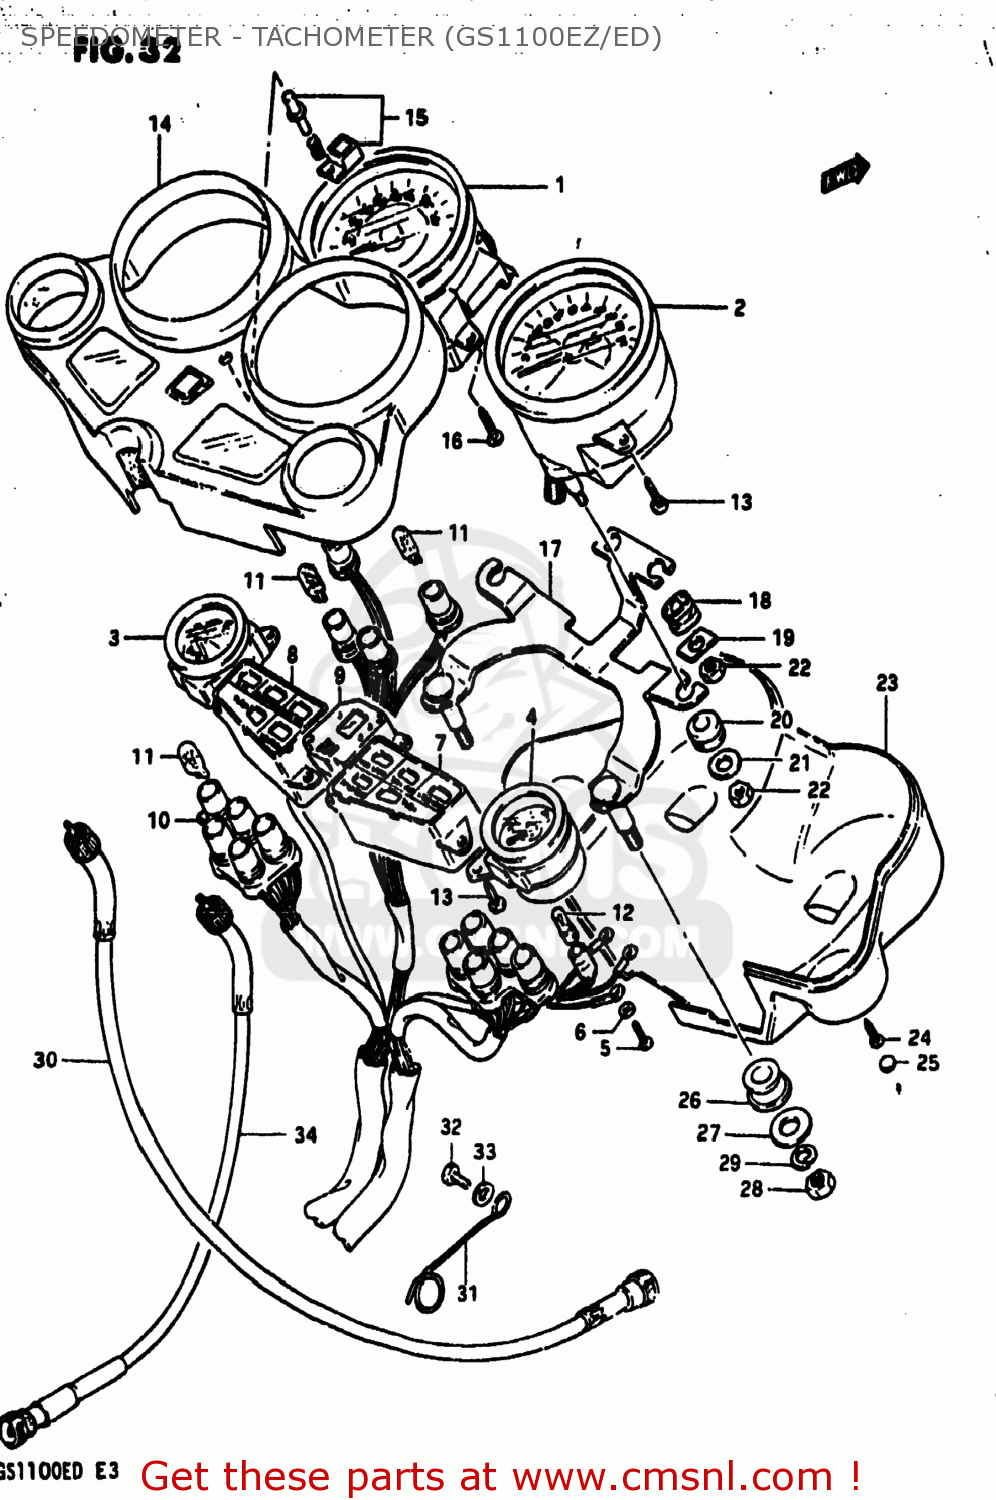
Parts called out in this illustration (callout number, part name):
1	SPEEDOMETER ASSEMBLY
2	TACHOMETER
3	METER,FUEL
4	METER,OIL TEMPERATURE
5	SCREW
6	WASHER
7	CASE,PILOT LAMP
8	CASE,PILOT LAMP
9	INDICATOR ASSEMBLY,GEAR POSITION
10	SOCKET,COMBINATION METER
11	BULB(12V3.4W,T10)
12	BULB(12V2W,STANLEY,A1272J)
13	SCREW
14	HOOD,METER
15	KNOB,TRIP METER
16	SCREW
17	BRACKET,COMBINATION METER
18	CUSHION,METER
19	WASHER,METER
20	CUSHION,METER
21	WASHER,METER
22	NUT
23	COVER,METER,UNDER
24	SCREW
25	CAP,METER LOWER CASE
26	CUSHION,METER BRACKET
27	WASHER (8.5X29X1.6)
28	NUT
29	LOCK WASHER
30	CABLE ASSY,SPEEDOMETER
31	CLAMP,SPEEDOMETER CABLE
32	BOLT, UPPER
33	WASHER
34	CABLE ASSEMBLY,TACHOMETER
